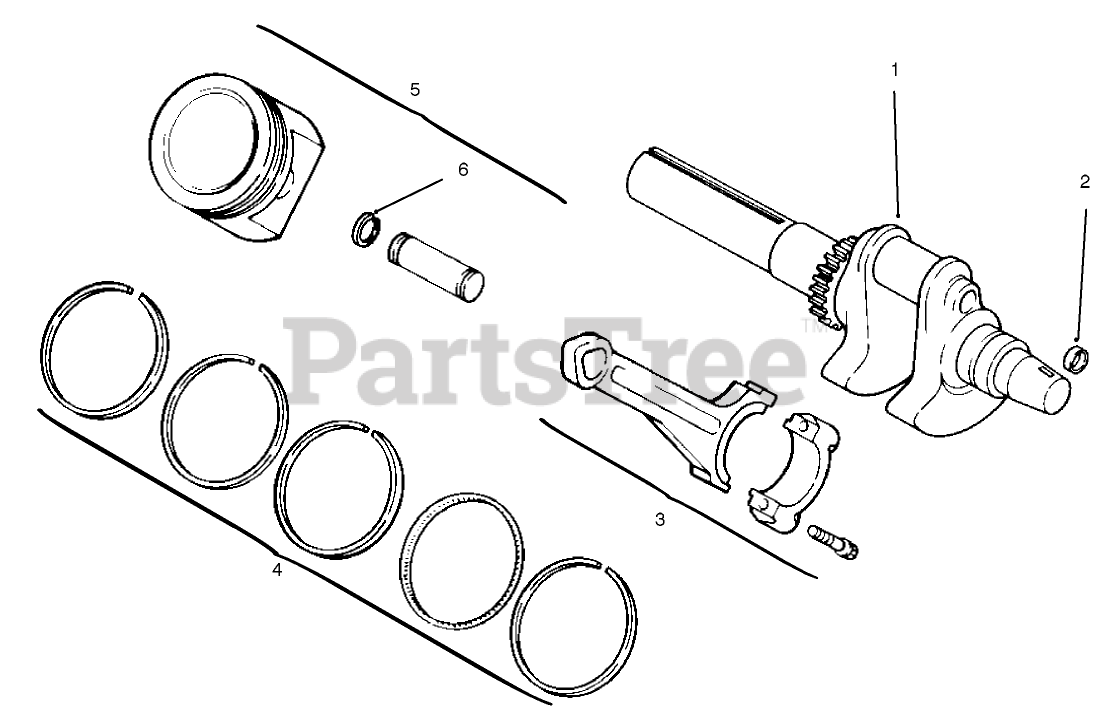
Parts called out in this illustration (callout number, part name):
1	Crankshaft
2	Plug-Cup
3	Connecting Rod STD
4	Ring Set(Std.)
5	Piston w/Ring Set (Std.)(Incl. Ref. # 4-6)
6	Retainer-Piston Pin
